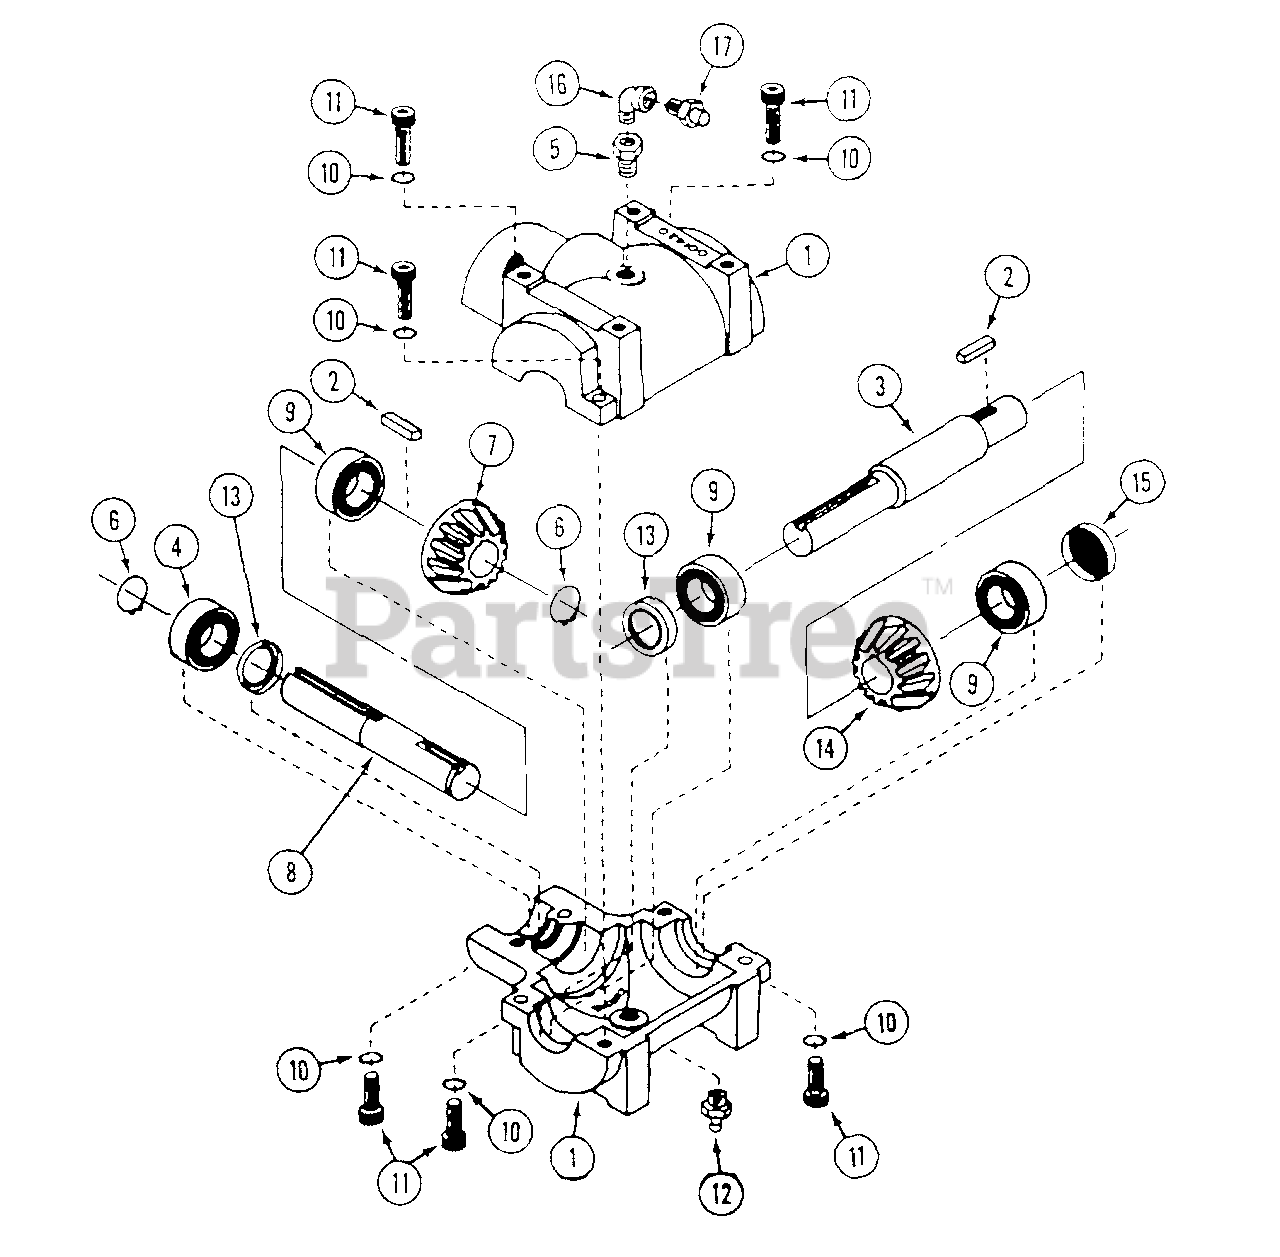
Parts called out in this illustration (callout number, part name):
1	HOUSING - half
2	KEY - 3/16" x 3/16" x 1"
4	BEARING - ball
5	BUSHING - pipe 1/4" x 1/8"
6	RING - retaining
7	GEAR - output shaft
8	SHAFT - output
9	BEARING - ball
10	LOCKWASHER
11	CAP SCREW - allen head
12	FITTING - grease 1/4" NPT
14	GEAR - input shaft
15	PLUG - expansion
16	ELBOW - street 1/8" x 90°
17	VALVE - relief
